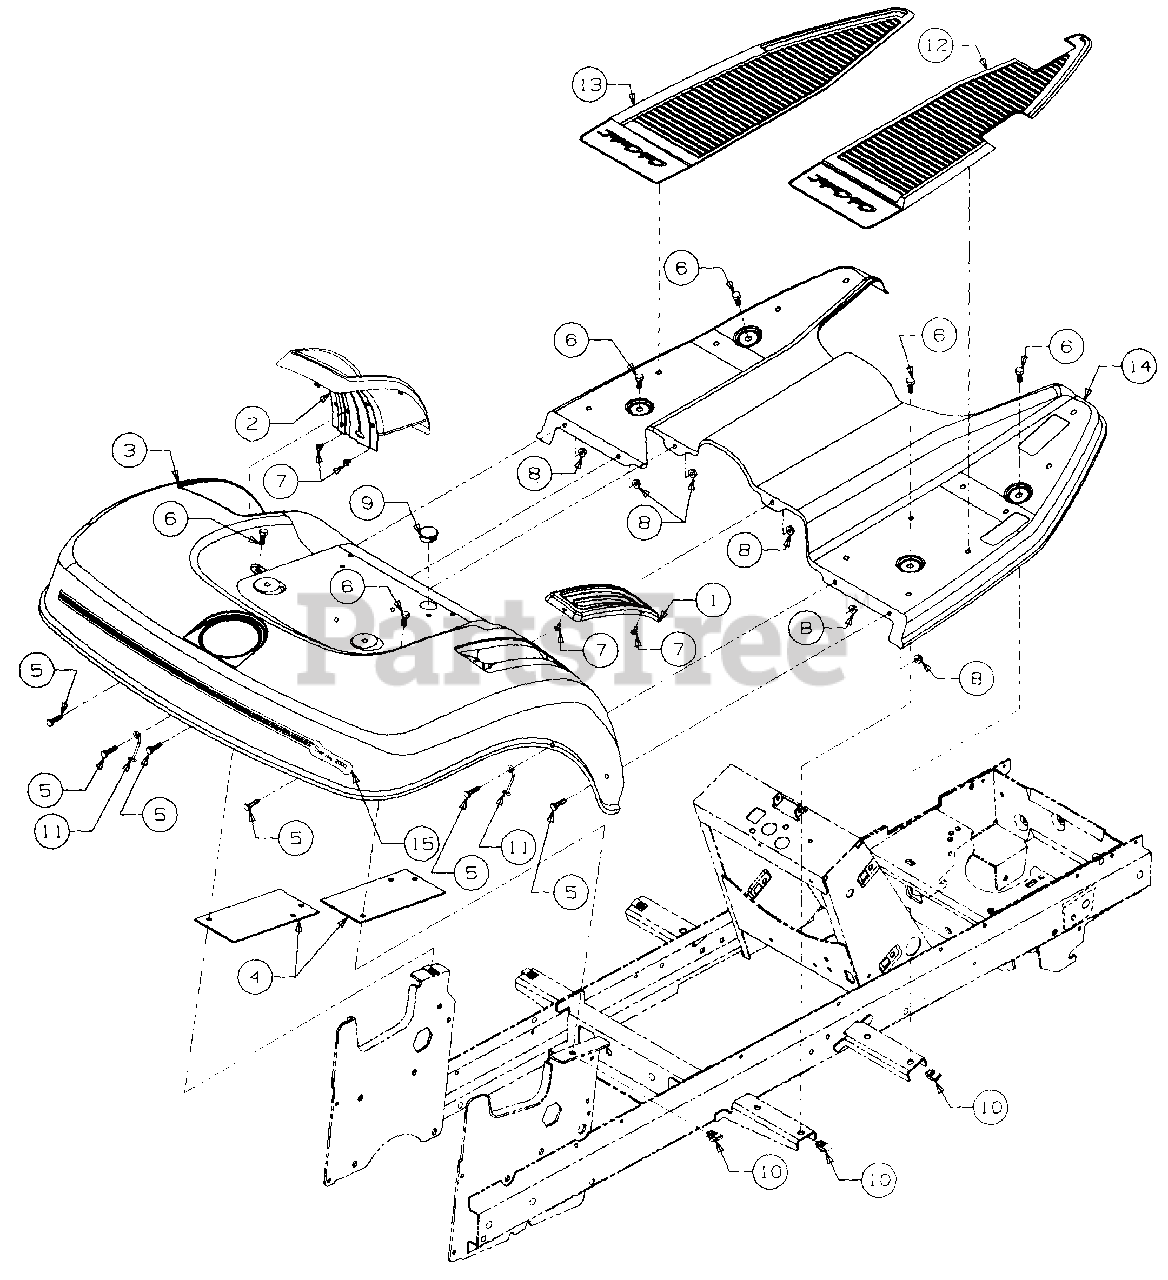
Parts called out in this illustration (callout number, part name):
1	Cover, Hydro Shifter
2	Cover, Implement Lift
6	Screw, Hex Wash Sf-Tapp 5/16-18 x .75 Lg
7	Screw, Hex Tapp, #10 x .38 Lg
8	Nut, Hex Flange Lock, 1/4-20
9	Bushing, Snap, 7/8 ID
10	U-Nut, 5/16-18
11	Retainer, Hook
12	Pad, RH Foot
13	Pad, LH Foot
14	Running Board w/Graphic
15	Graphic, Rear Fender
